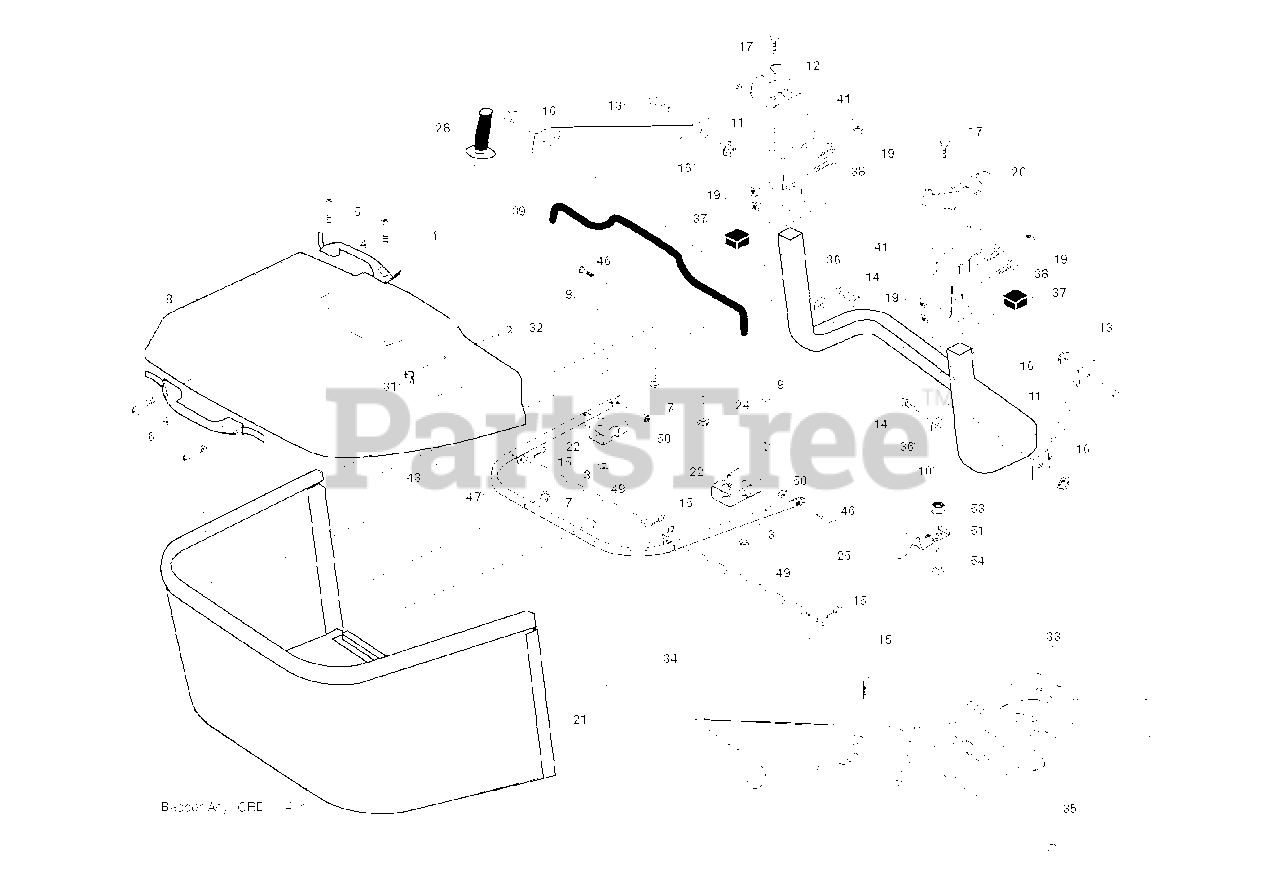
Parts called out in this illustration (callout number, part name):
1	TUBE.PNT.HDL.BAGGER.
3	NUT T
5	SCREW.PAN.HEAD
8	Bagger Cover and Seal Assembly, CRD 505
11	BRACKET
14	BOLT-HEX EAK
15	RETAINER-SPRNG RB
16	NUT LOCK FLG 3/8-16 UNC
17	BOLT
19	NUT LOCK HEX FLANGE 5/16-18
20	BRKT.PIVOT.RH.CRD
21	BAGGER.ASM.CRD.2007
22	BRACKET.BAGGER.SD.
24	TUBE
28	GRIP.HANDLE.BLACK
31	RETAINER CLIP
32	RIVET,DRILLED
33	MULCHING.PLUG.1078.CRD.NON-TEX
35	PIN
38	BOLT.5/16-18X2.5
39	SEAL.BAGGER.CRD
41	BRACKET.BAGGER.SD.
43	PLUG, TUBING END
46	BOLT.CARRIAGE.5/16-18
50	NUT.71038.31-18.HEX.NYLOCK
53	NUT
54	BOLT
